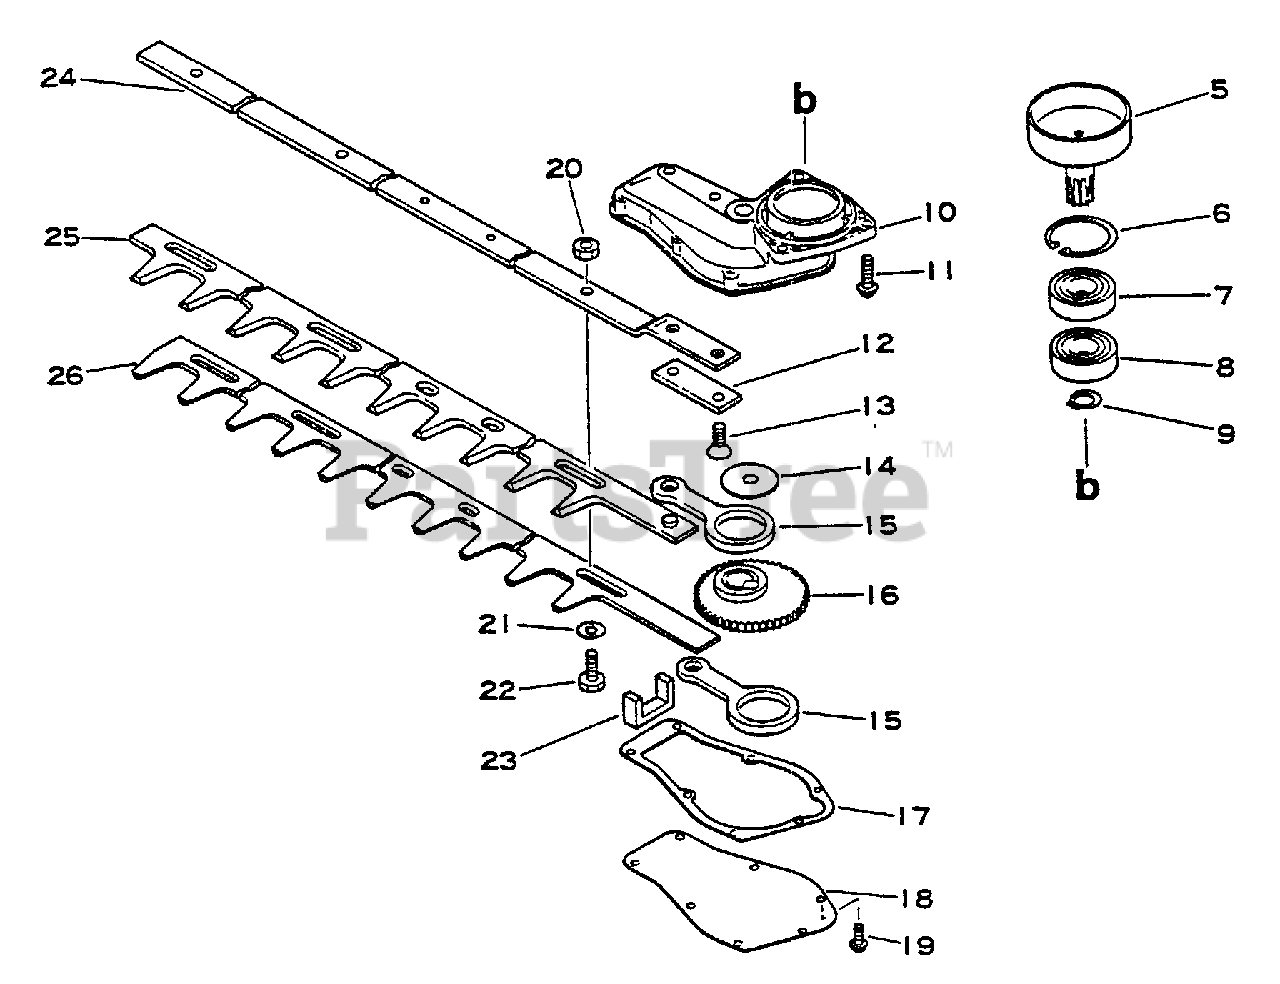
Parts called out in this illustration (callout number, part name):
5	DRUM, CLUTCH
6	RING, RETAINING - 35
7	BEARING, BALL - 6202
8	BEARING, BALL - 6202
9	RING, RETAINING - 14
10	CASE, GEAR
11	SCREW - 5X20
13	SCREW - 6X18
15	ROD, CONNECTING
16	GEAR - DRIVE
17	GASKET, GEAR CASE
18	LID, GEAR CASE
19	SCREW - 4X10
21	WASHER - 6
23	SEAL, FELT
24	SUPPORT, BLADE
25	BLADE - UPPER
26	BLADE - LOWER
